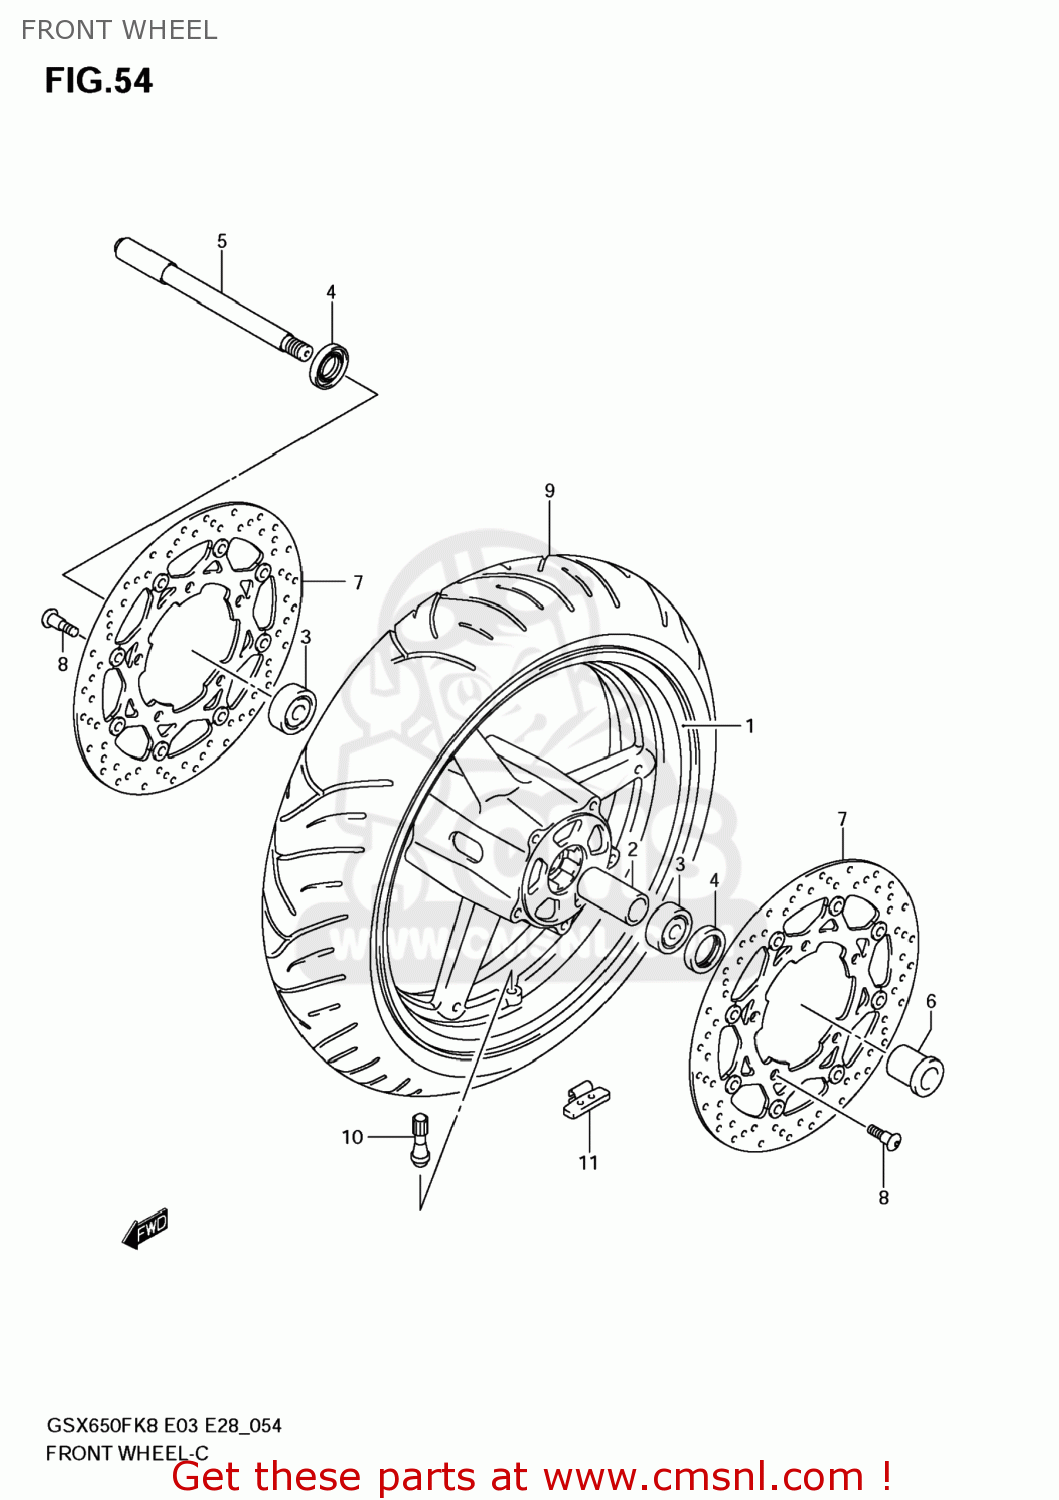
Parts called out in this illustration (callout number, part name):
1	WHEEL,FR(17M/CXMT3.50)
2	SPACER,FR HUB BEARING
3	BEARING
4	SEAL,OIL(28X47X7)
5	AXLE,FR
6	SPACER,FR AXLE,L
7	DISC,FR BRAKE
8	BOLT(8X21)
9	TIRE,FR
10	VALVE ASSY,WHEEL RIM(TR412)
11	BALANCER,WHEEL(10G)
